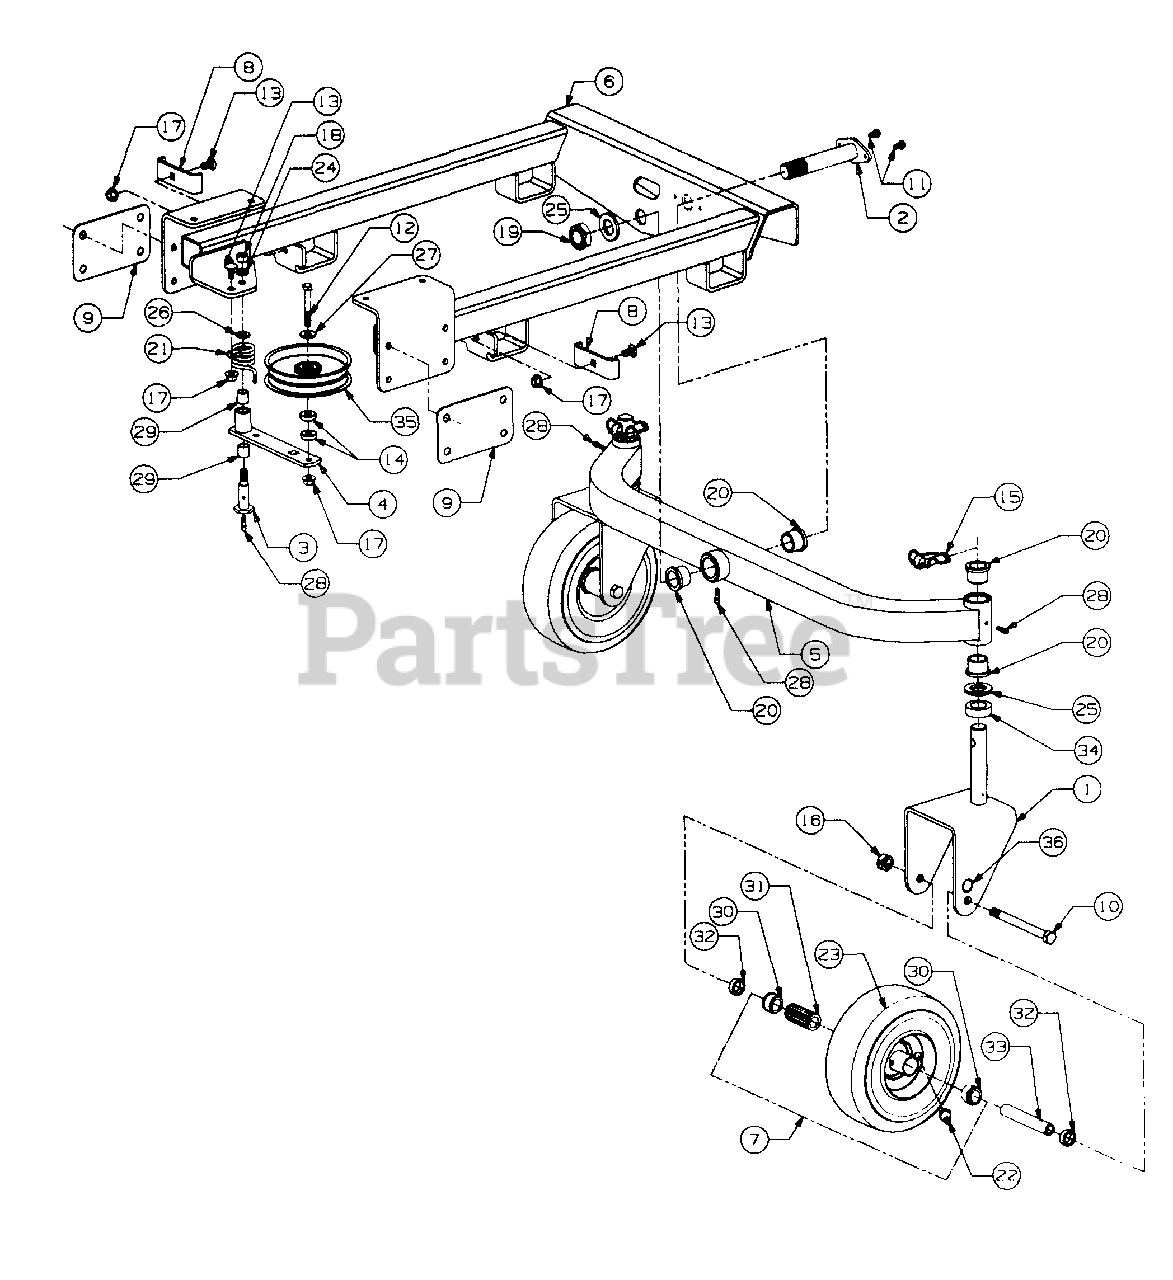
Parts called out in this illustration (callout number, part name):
2	Pin, Axle Pivot
3	Bolt, Shoulder
4	Arm Assy, Idler
5	Axle Assy, Front
7	Wheel Assy, Caster
8	Stop, Wear Bar
10	Screw, Hex Cap, 1/2-20 X 5.50 Lg
11	Screw, Hex Wash Hd TT-Tap, 1/4-20 X .50 Lg
12	Screw, Hex Cap, 3/8-16 X 2.5 Lg GR5
13	Bolt, Sht Nk Carriage, 3/8-16 X .75 Lg GR5
14	Spacer, .380 X 1.0 X .320
15	Pin, Klik
16	Nut, Hex Center Lock, 1/2-20
17	Nut, Hex Flanged Lock, 3/8-16
18	Nut, Hex, 7/16-14 GR5
19	Nut, Hex Lock, 1-14
20	Bearing, Flange
21	Spring, Torsion
22	Valve, Tubeless Air
23	Tire, Smooth, 9.0 X 3.50 X 4
24	Washer, Lock, 7/16
25	Washer, Special
26	Washer, Flat, .469 X .875 X .105 Thk
27	Washer, Flat, .406 X 1.0 X .105 Thk
28	Fitting, Lube
29	Bearing, Sleeve
30	Bearing, Graf Oil Flange
31	Bearing, Roller
32	Spacer, .790 ID X .347 Lg
33	Spacer, Wheel
34	Spacer, 1.015 X 1.62 X .50 Lg
35	Pulley, 5" Idler
36	Label Inflation
